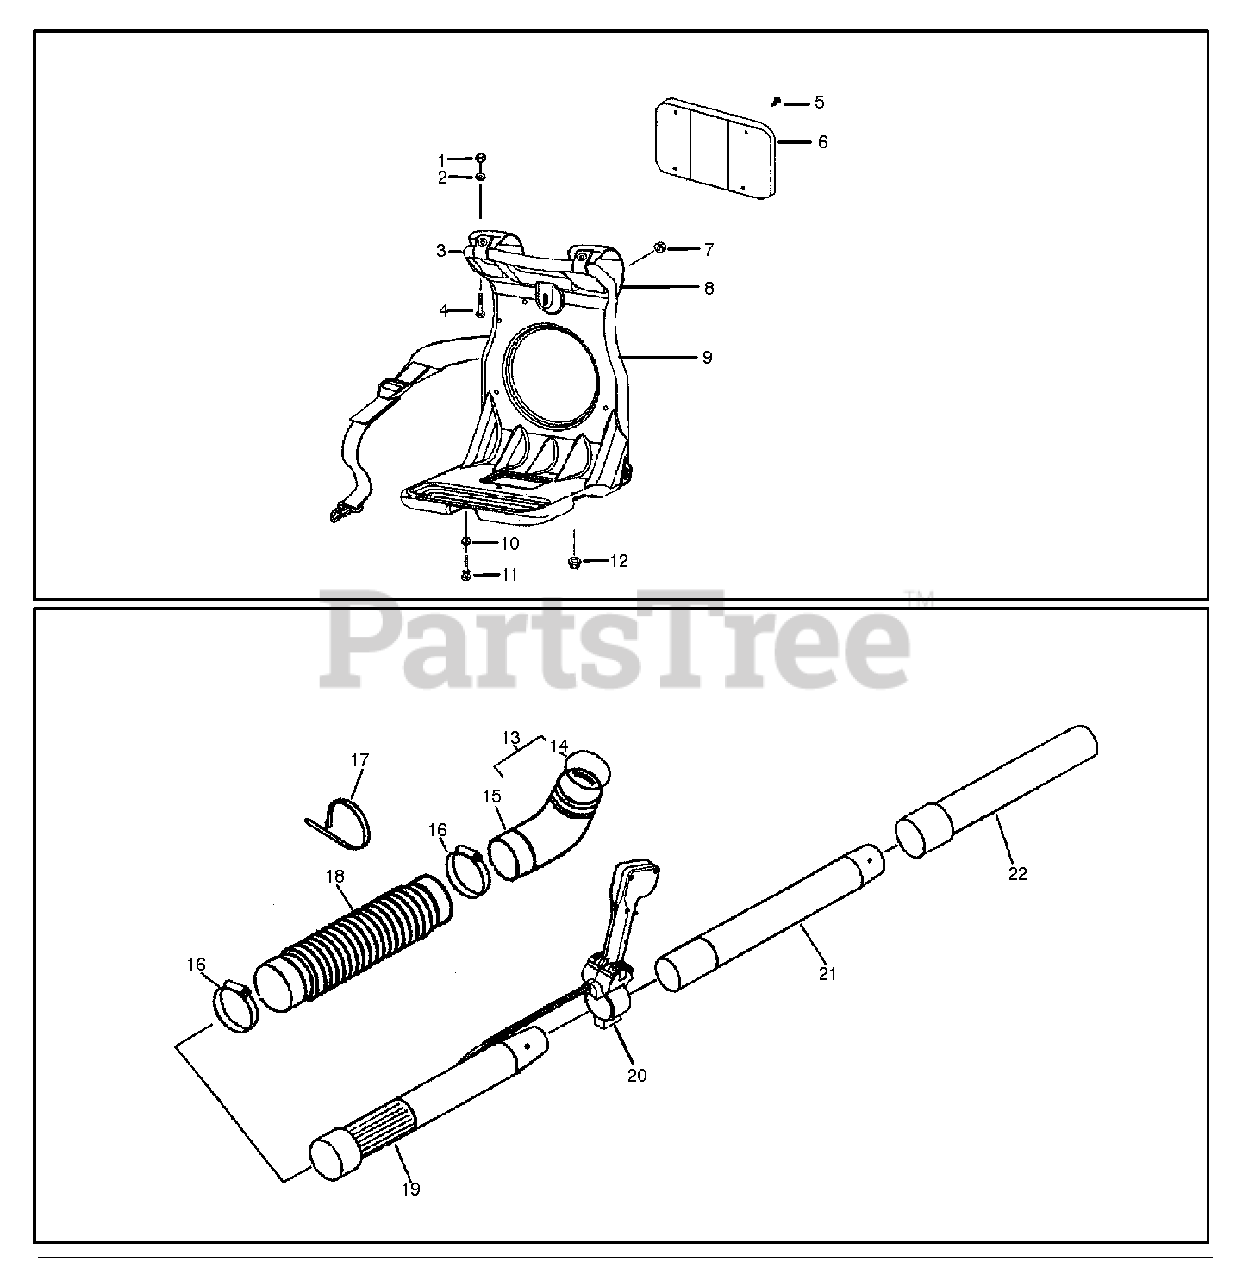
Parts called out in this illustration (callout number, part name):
1	FLANGE NYLON NUT M6
3	SHOULDER BAND
6	KNAPSACK PAD
8	SHOULDER BAND
9	KNAPSACK FRAME
11	SCREW W/SW M6 X 25 375L0625
13	ELBOW PIPE C.P.
15	ELBOW PIPE
16	HOSE BAND
17	WIRE BAND
18	FLEX PIPE
19	BASE PIPE
20	THROTTLE LEVER ASSY
21	MIDDLE PIPE
22	BEND PIPE
